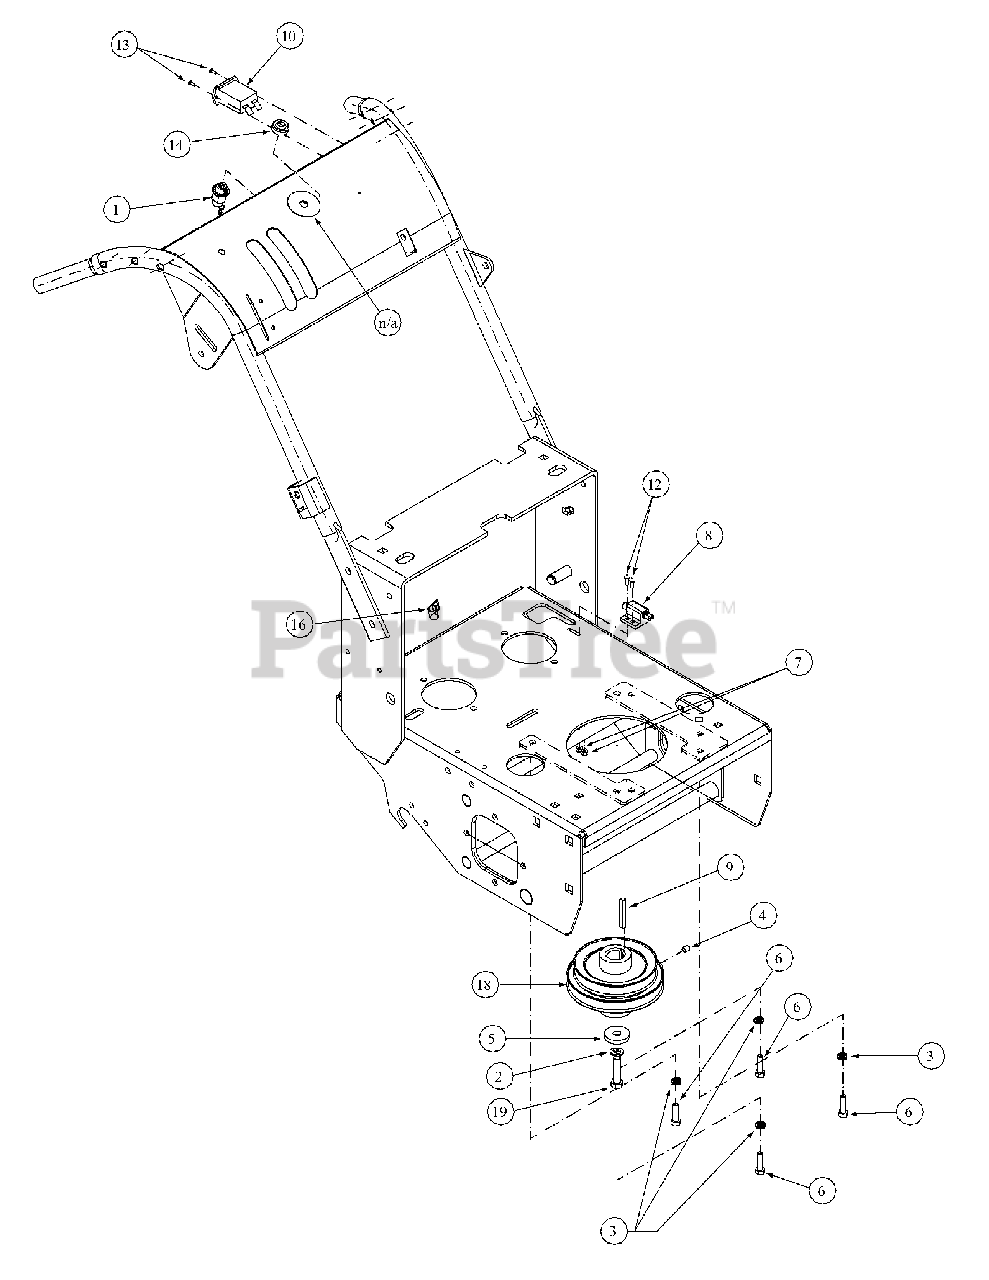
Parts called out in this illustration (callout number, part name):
1	On/Off Ignition Switch
2	Lock Washer, M10
3	Lock Washer, 5/16
4	Nylock Screw, 5/16-18 x 3/8
5	Clutch Washer
6	Capscrew, M8-1.25 x 30
7	Lock Nut, Nylon Insert, #10-32
8	Delta Switch
9	Key Stock, 1/4 x 1/4 x 2
10	Meter, Hour
10	Belt, Hydro Pump
12	Phil. He. Mach. Screw #10-32 x 5/8
13	Rivet
14	Nut w/Cap, 5/8-32 Ignition
14	Kawasaki 14 HP Engine
16	Support Clamp, 3/8 OD
16	Harness Wire
18	Double Pulley
19	Capscrew, M10-1.5 x 50mm
